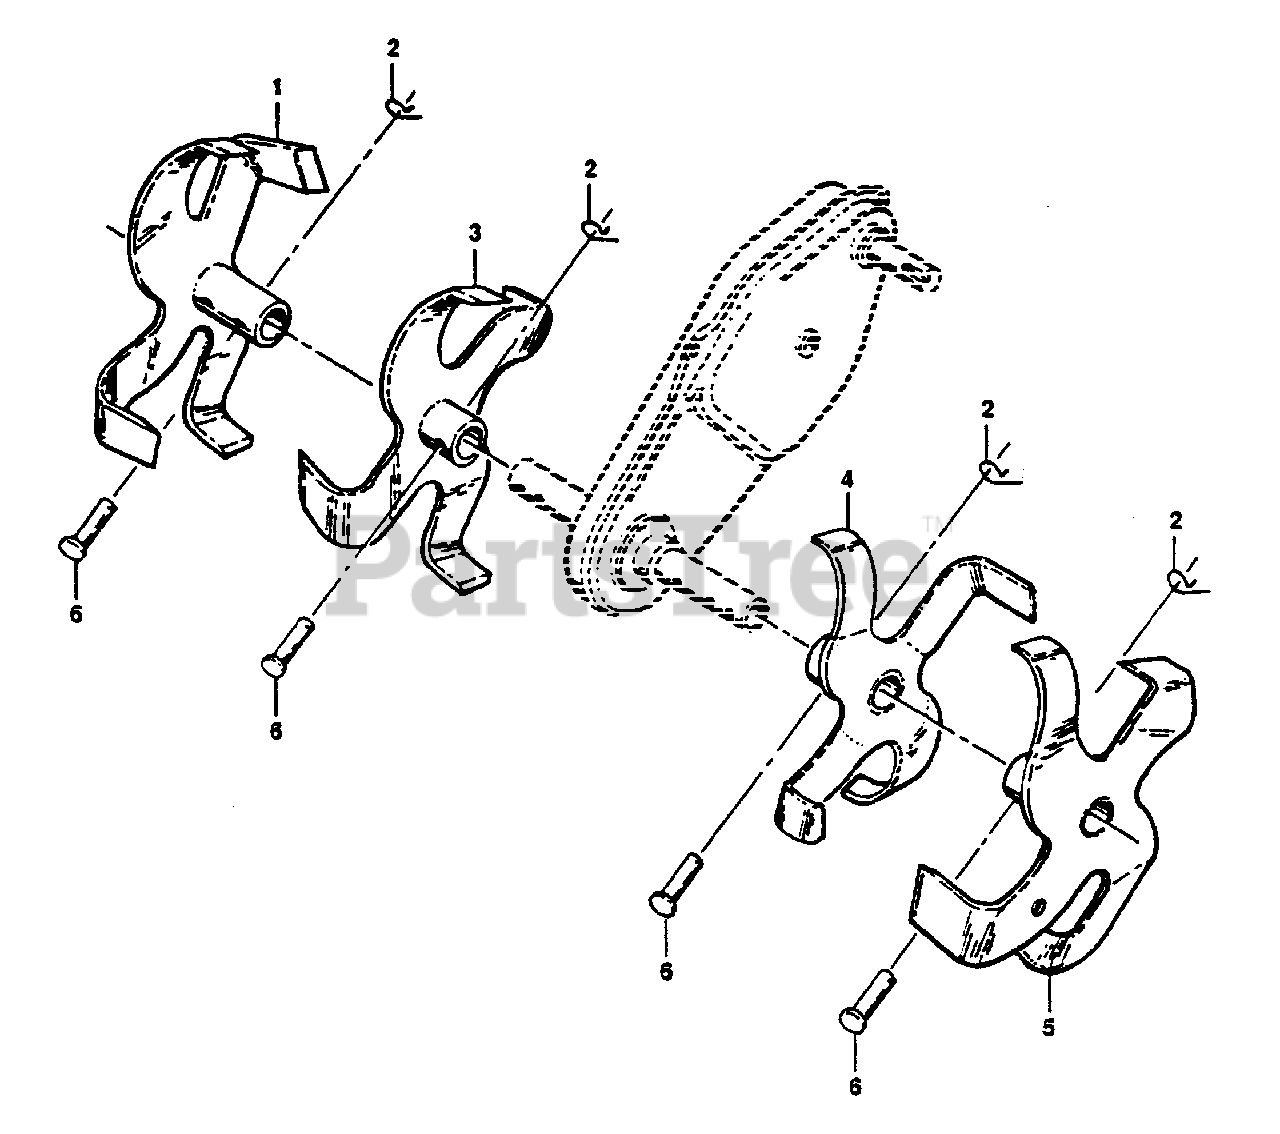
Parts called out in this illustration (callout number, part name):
1	Tine, Outer, R.H. (AYP part number)
2	Clip, Hairpin (AYP part number)
3	Tine, Inner, R.H. (AYP part number)
4	Tine, Inner, L.H. (AYP part number)
5	Tine, Outer, L.H. (AYP part number)
6	Pin, Clevis (AYP part number)
